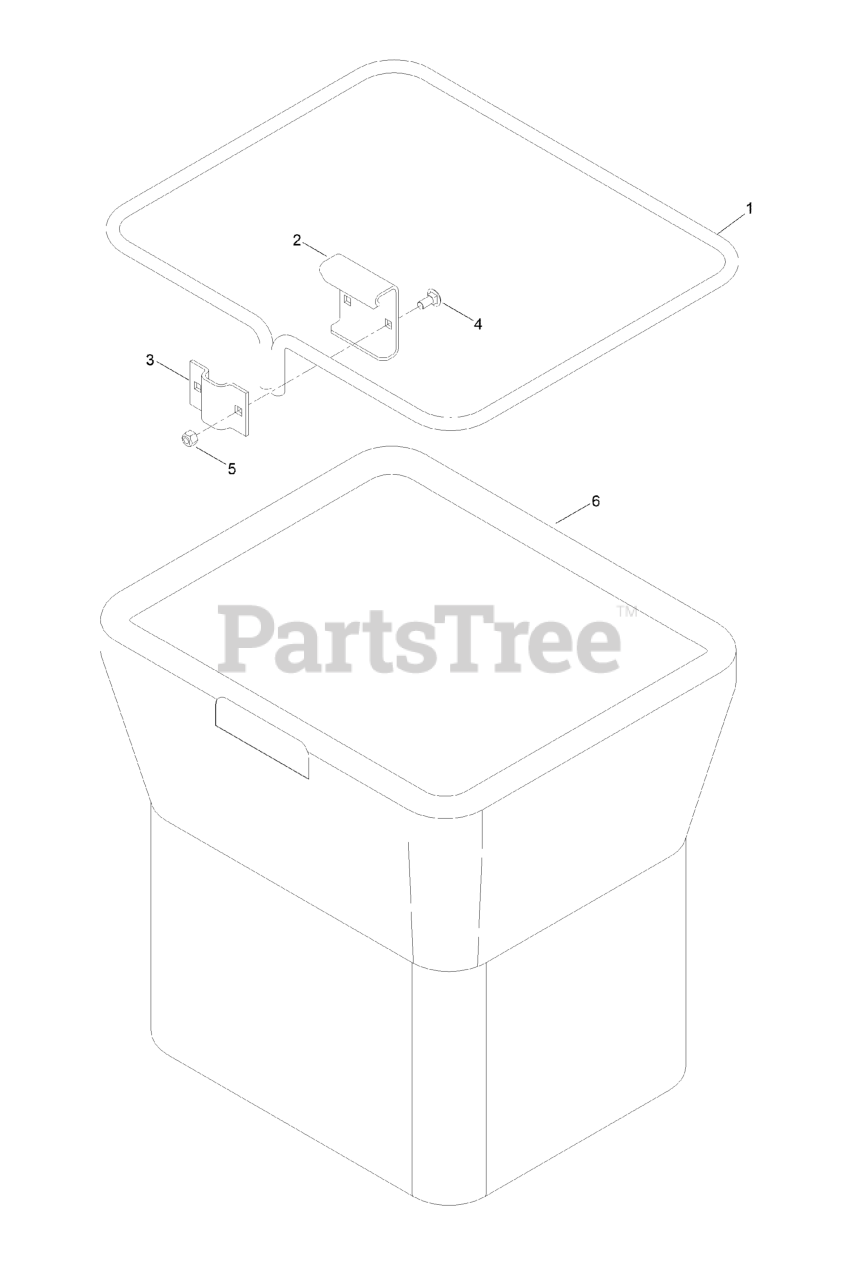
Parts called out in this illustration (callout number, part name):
1	FRAME-BAG
2	HANGER-BAG
4	BOLT-CARR
5	NUT-HEX
